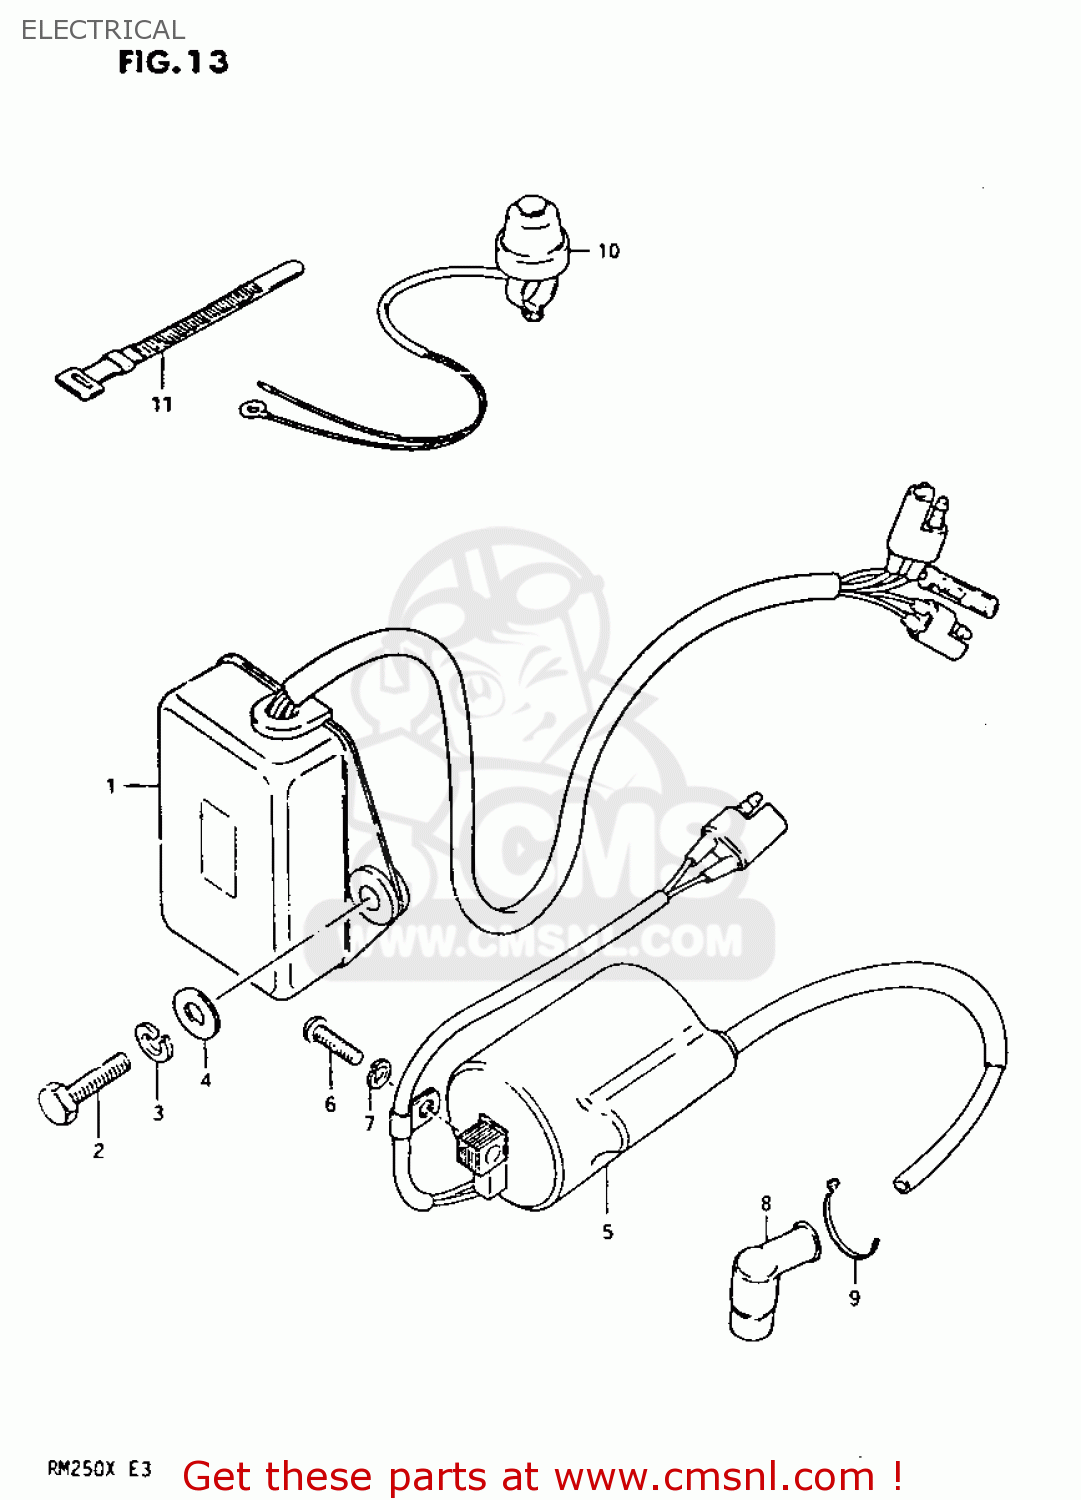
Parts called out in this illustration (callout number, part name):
1	CDI UNIT
2	BOLT
3	WASHER,LOCK
4	WASHER(6.5X16X1.2)
5	COIL ASSY,IGNITION
6	SCREW 5X20
7	LOCK WASHER
8	CAP,SPARK PLUG
9	CLAMP
10	SWITCH ASSEMBLY
11	CLAMP(L:120)
